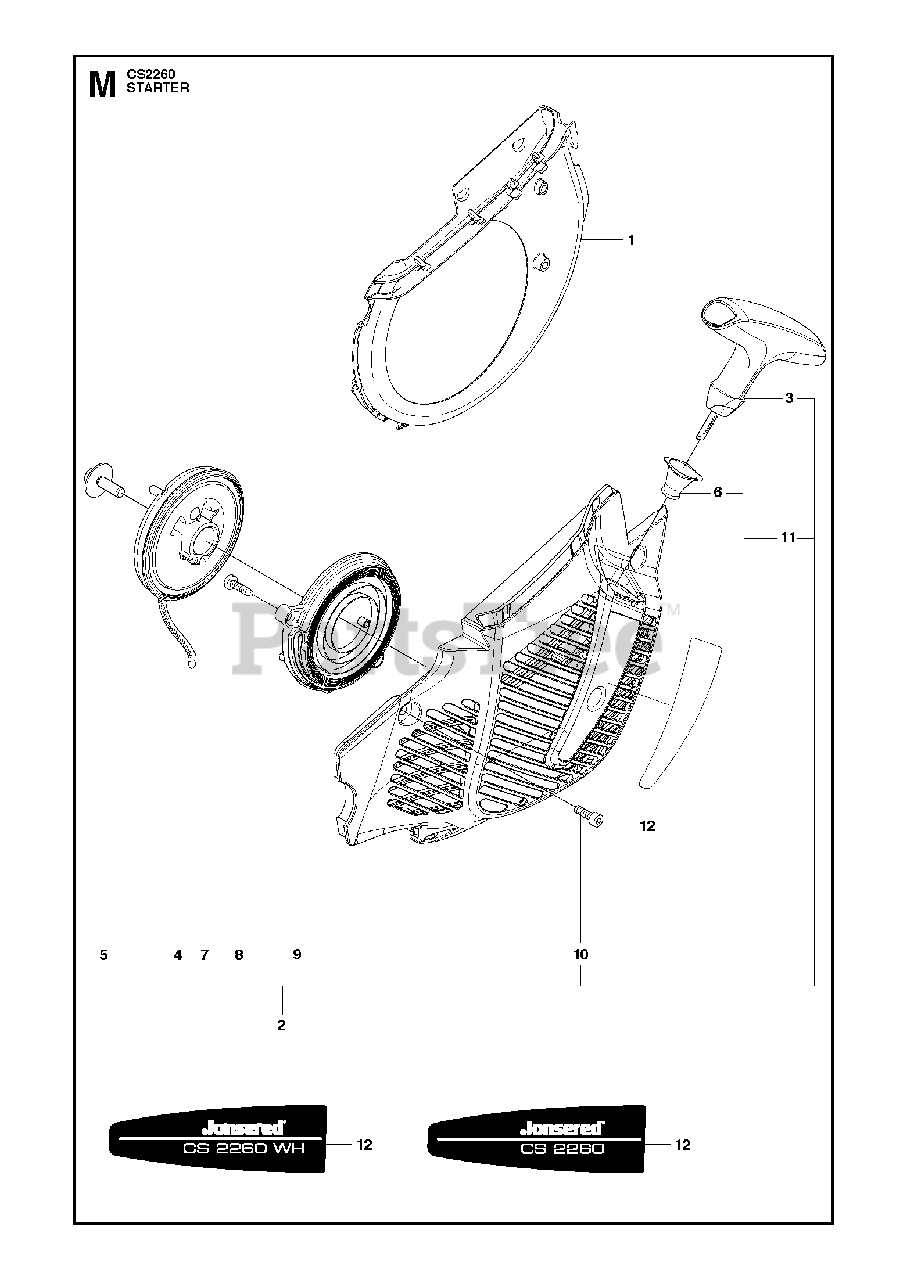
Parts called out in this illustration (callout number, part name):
1	COOLING AIR CONDUCTOR
2	STARTER ASSY
3	STARTER HANDLE
4	STARTER ROPE
5	SCREW
6	SLEEVE
7	STARTER PULLEY ASSY
8	SCREW
9	SPRING CASSETTE ASSY
10	SCREW
11	STARTER HOUSING
12	DECAL JONSERED 60CC STARTER CO
